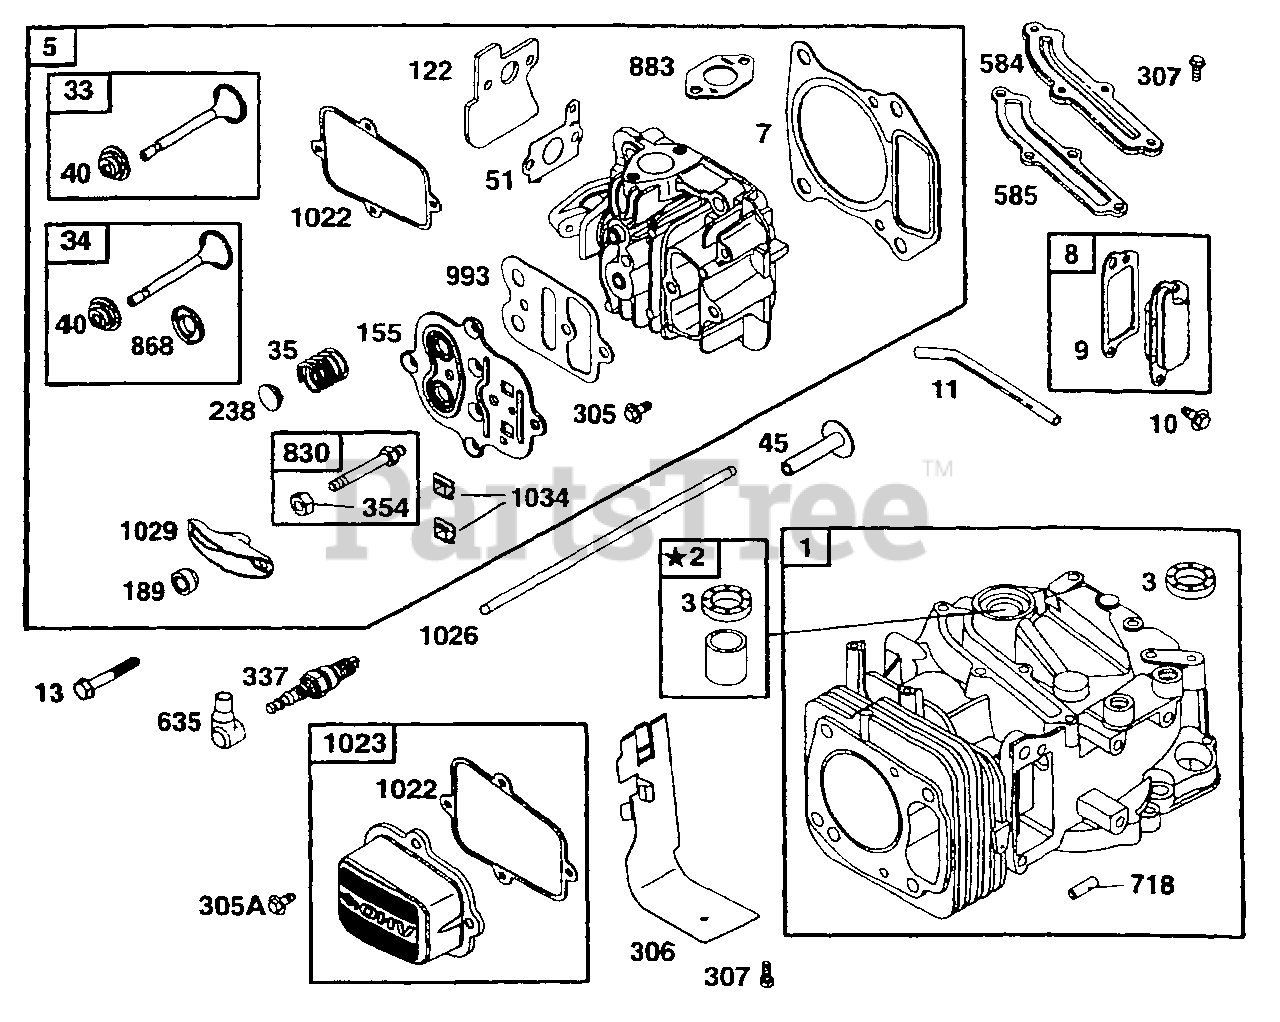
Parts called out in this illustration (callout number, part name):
1	Cylinder Assembly
3	Seal-Oil
5	Cylinder Head
7	Cylinder Head Gasket
8	Breather Assembly
9	Breather Gasket
10	Screw-Hex
11	Breather Tube
13	Screw-Hex
33	Exhaust Valve
34	Intake Valve
35	Valve Spring
40	Valve Retainer
45	Valve Tappet
51	Intake Gasket
122	Carburetor Spacer
155	Cylinder Head Plate
189	Rocker Arm Ball
238	Valve Cap
305	Screw-Hex
305A	Screw-Hex
306	Cylinder Shield
307	Screw-Hex
337	Spark Plug
584	Breather Passage Cover
585	Breather Passage Gasket
635	Spark Plug Boot
718	Locating Pin
830	Rocker Arm Stud
868	Valve Seal
883	Exhaust Gasket
993	Plate Gasket
1022	Rocker Cover Gasket
1023	Rocker Cover
1026	Push Rod
1029	Rocker Arm
1034	Push Rod Guide
